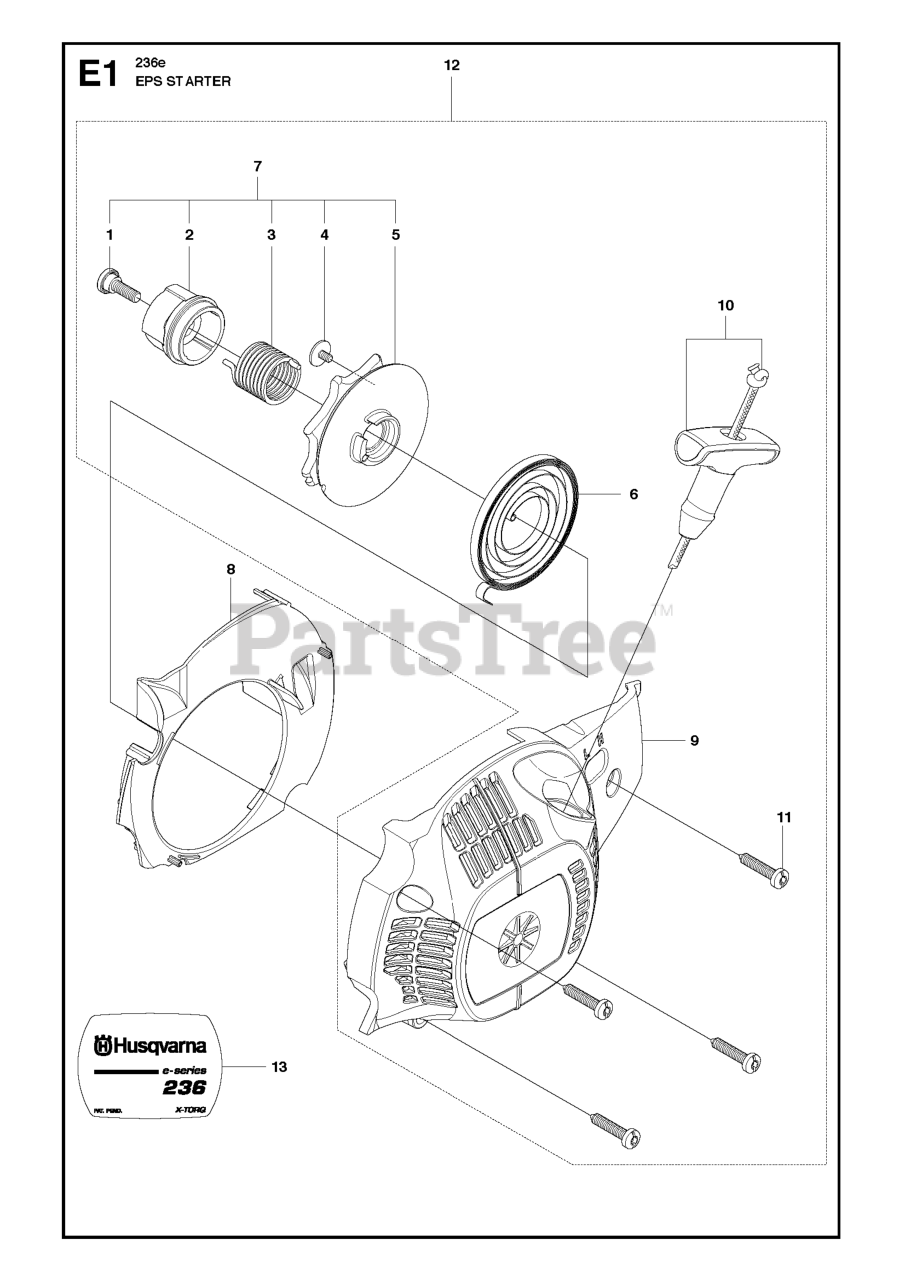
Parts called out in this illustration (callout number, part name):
1	SCREW SHOULDER
2	HUB STARTER EPS
3	SPRING EPS
5	STARTER PULLEY
6	SPRING STARTER
7	KIT EPS STARTER
9	FAN HOUSING
10	STARTER ROPE W/HANDLE
11	SCREW M5.38-14X22.225MM
12	KIT COMPLETE EPS
